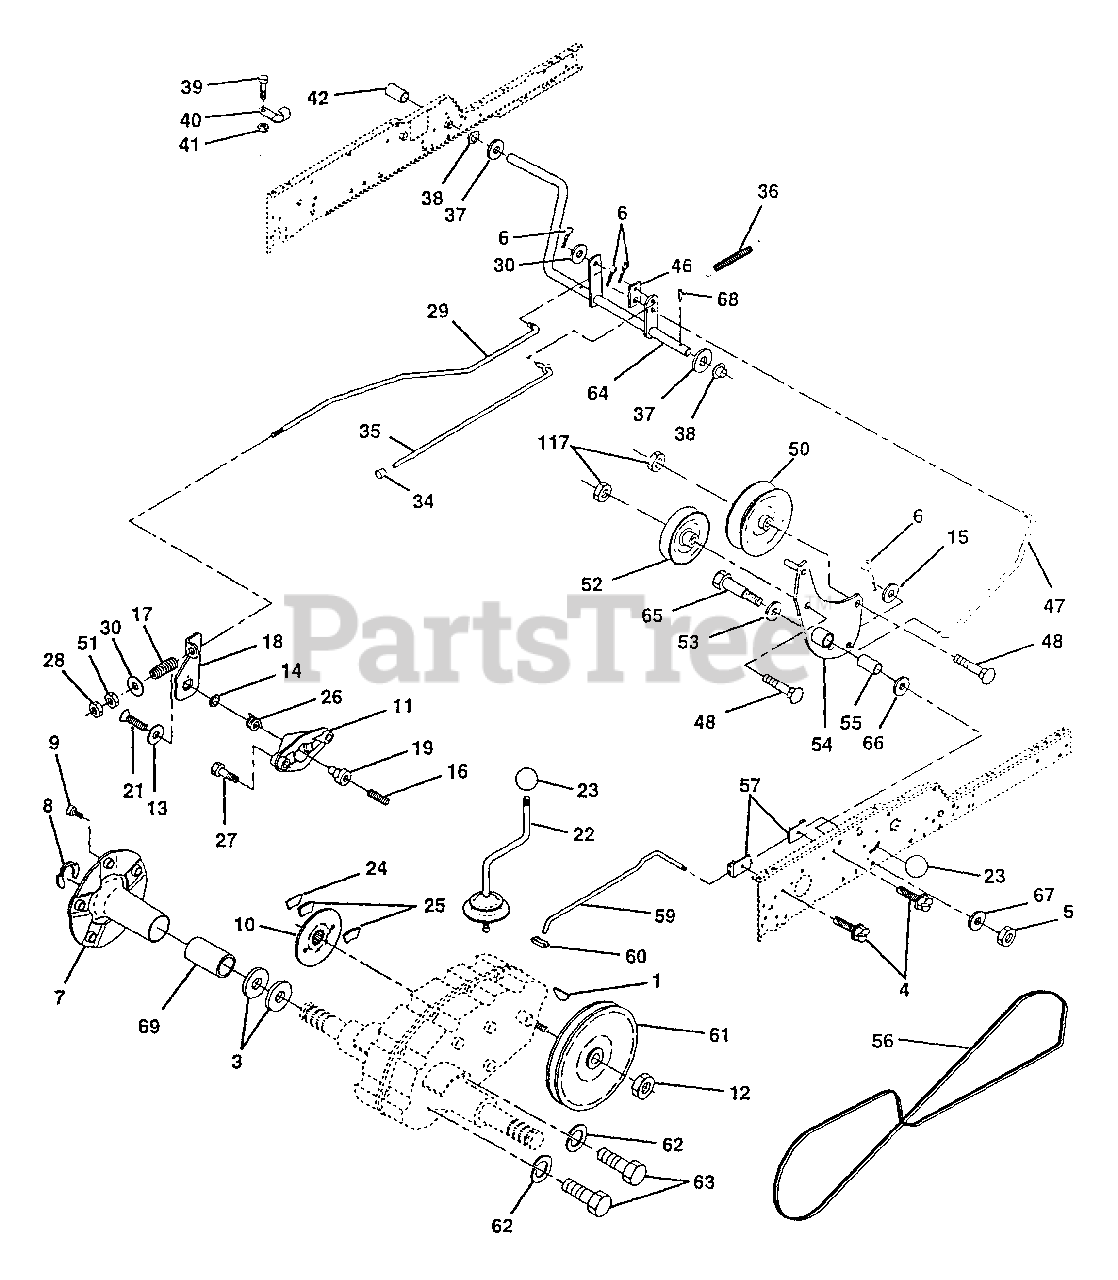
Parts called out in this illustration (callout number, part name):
1	Key Woodruff (AYP part number)
3	Washer Thrust Axle Harden
4	Screw Thdrol 5/16-18 x 1/2
5	Nut Crownlock 3/8-16
6	Pin Cotter 1/8 x 3/4
7	Wheel Hub Asm. (AYP part number)
8	Ring Klip
9	Bolt Hub
10	Disc Brake
11	Yoke Brake Disc
12	Locknut 1/2-20
13	Washer Special
14	Bushing
15	Washer 13/32 x 13/16 x 16 Ga
16	Set Screw 1/4-28 x 3/4
17	Spring
18	Lever Brake
19	Cam Brake Disc
21	Screw Flat Head 1/4-28 x 3/4
22	Gearshift Lever Assembly
24	Support Puck Brake
25	Puck Brake Top
26	Spring Return
27	Screw Hex Wsh Thd 5/16-18 x 1-3/4
28	Nut Hex Jam 3/8-16
29	Brake Rod
30	Washer 13/32 x 1 x 16 Ga
34	Cap Plunger
35	Rod Parking Brake
36	Spring Extension
37	Washer 25/32 x 1-1/4 x 16 Gauge
38	Nyliner
39	Screw Fin #10-24 x 1
40	Actuator Interlock Switch (AYP part number)
41	Nut Lock #10-24 (AYP part number)
42	Cover Pedal
46	Retainer Spring
47	Clutch Rod
48	Bolt Carr. SH 3/8-16 x 1-1/2 Gr. 5
50	Pulley Idler Flat (AYP part number)
51	Nut Crownlock 3/8-16 Unc
52	Pulley Idler Grooved
53	Washer Hardened
54	Clutch Arm Asm (AYP part number)
55	Bearing, Idler
56	V-Belt
57	Bracket Shift Rod Hi-Lo
59	Shift Rod Hi-Lo
60	Spring Clip Connecting Link
61	Pullery Transaxle (AYP part number)
62	Washer Lock 7/16
63	Bolt Fin Hex 7/16-14 x 1-1/4 (AYP part number)
64	Shaft Clutch/Brake Pedal
65	Bolt Shoulder
66	Washer Hardened
67	Washer 13/32 x 13/16 x 12 Ga.
68	Pin Roll
69	Hub Cover
117	Nut Lock Flg 3/8-16 UNC (AYP part number)
